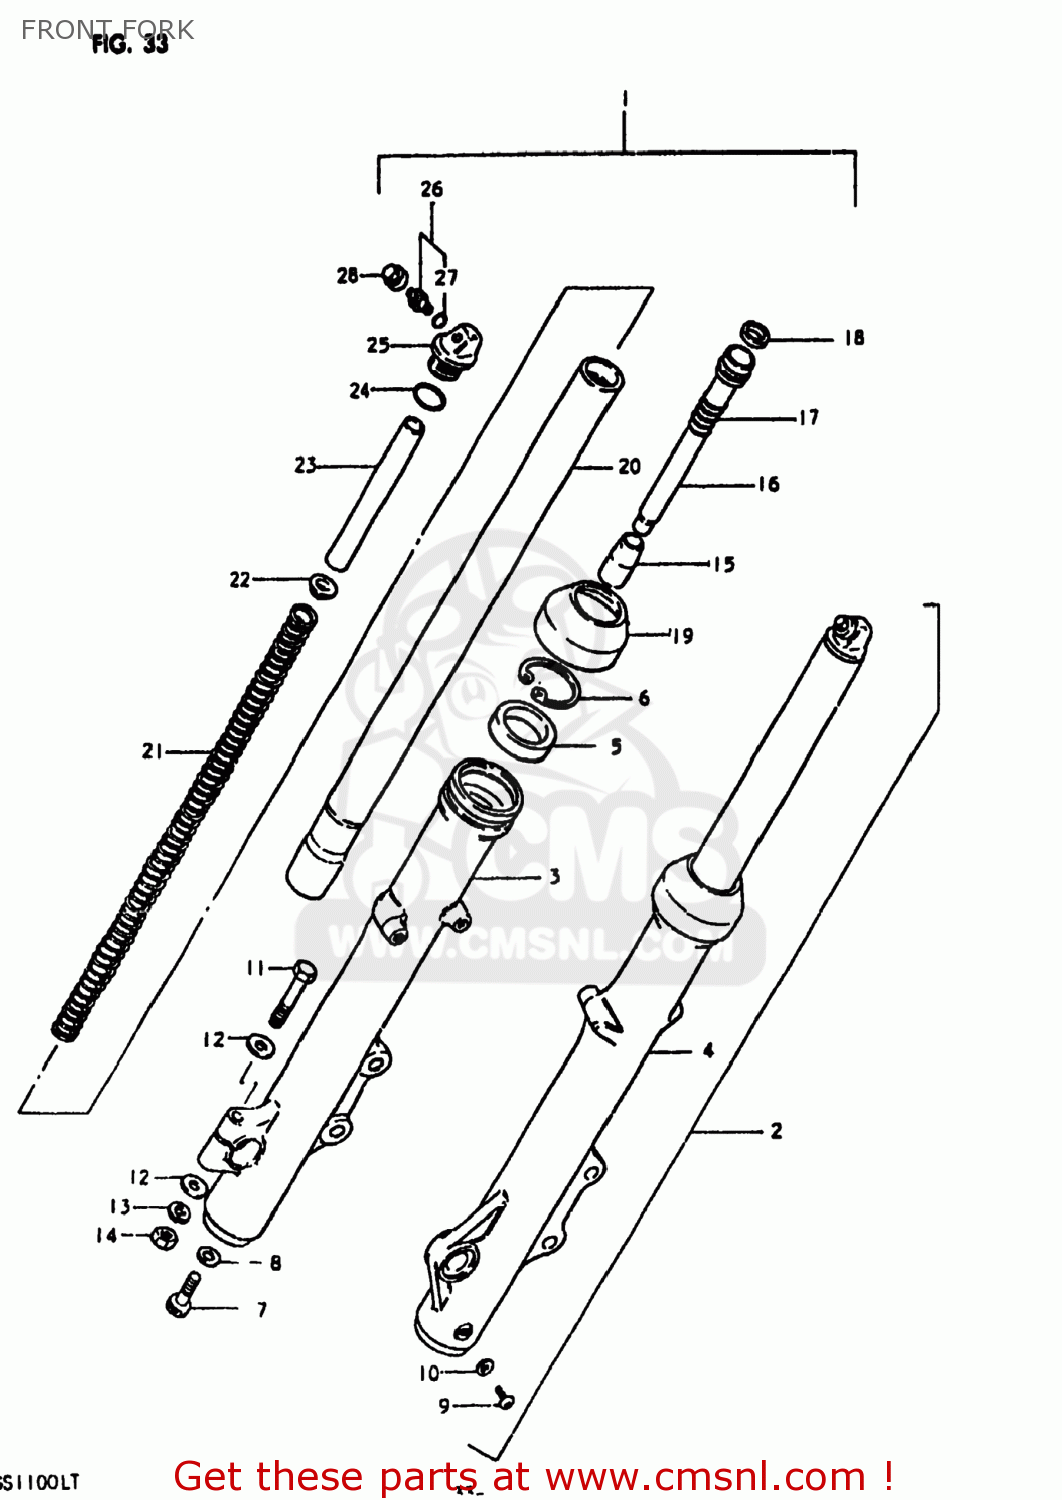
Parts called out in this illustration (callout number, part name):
1	DAMPER ASSEMBLY,RIGHT
2	DAMPER SET
3	TUBE,FORK,OUTER,RIGHT
4	TUBE,OUTER,LEFT
5	OIL SEAL,FRONT FORK
6	RING,STOPPER
7	BOLT,FORK CYLINDER(10X25)
8	GASKET (NAS)
9	SCREW
10	GASKET,DRAIN,PLUG (NAS)
11	BOLT 8X50
12	WASHER
13	WASHER,LOCK,8.
14	NUT
15	PIECE,OIL LOCK
16	CYLINDER,FRONT FORK
17	SPRING,REBOUND
18	RING,PISTON
19	SEAL,DUST
20	TUBE,FORK,INNER
21	SPRING,FRONT FORK
22	GUIDE,FRONT FORK SPRING C
23	COLLAR,SPRING
24	O RING
25	CAP
26	VALVE
27	O RING
28	CAP,VALVE
